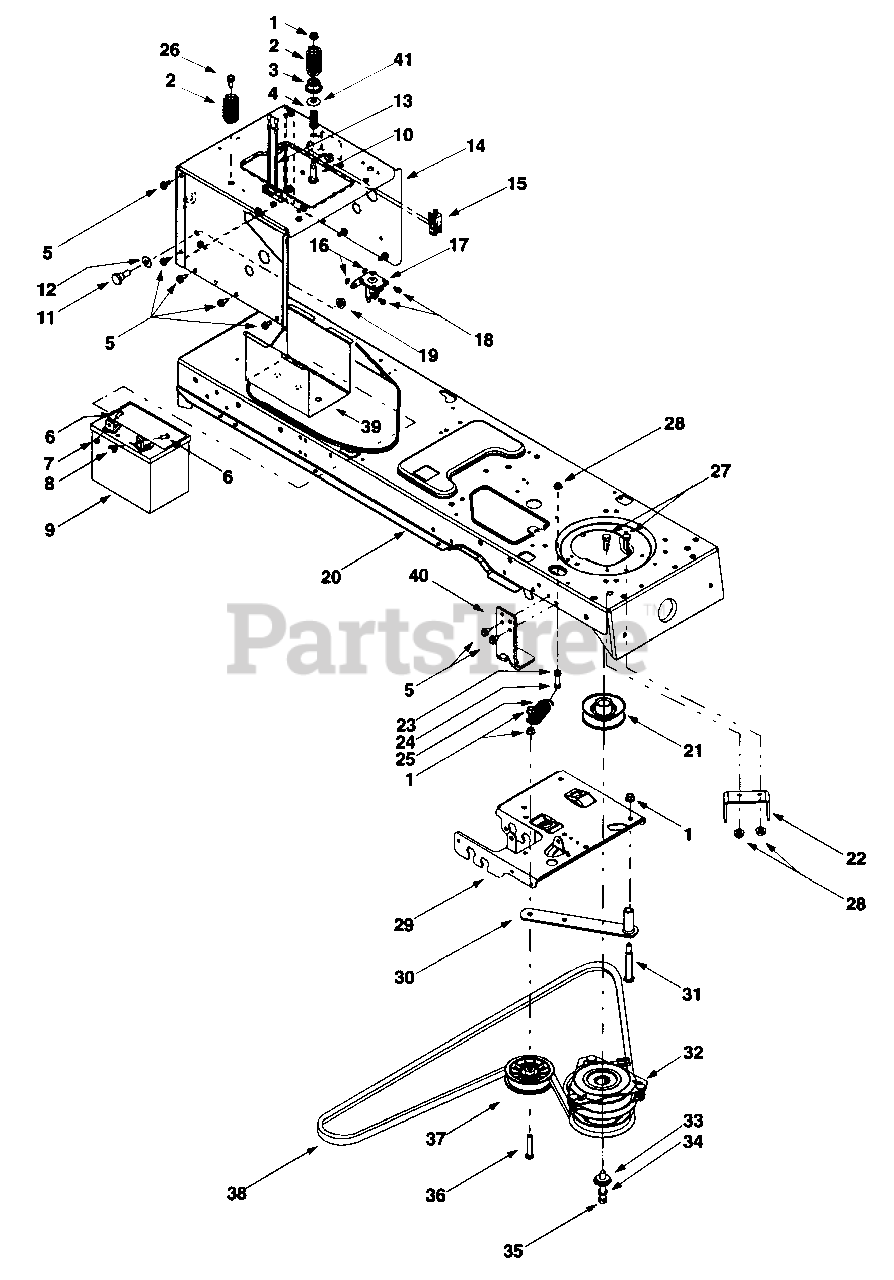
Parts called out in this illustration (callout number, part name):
1	Flange Lock Nut, 3/8-16
2	Compression Spring, 1.318 x 2.37
3	Spacer Cup, 1.5 OD
4	Compression Spring, .66 OD x 1.5
5	Self Tapping Screw, 5/16-18 x .625
6	Hex Cap Screw, 1/4-20 x .62
7	Hex Sems Nut, 1/4-20
8	Wing Nut, 1/4-20
9	12-volt Battery, 270 CCA
10	Shoulder Screw, .5 x 1.25, 3/8-16
11	Shoulder Screw, .625 x .5, 7/16-20
12	Bell Washer, .45 x 1.0 x .062
13	Battery Strap
16	Lock Washer, 1/4
17	Solenoid, 12-Volt, 100 Amp
18	Self Tapping Screw, 1/4-20 x .5
19	Flange Lock Nut, 7/16-20
24	Hex Cap Screw, 5/16-18 x 1.75 (Grade 5)
25	Extension Spring, 1.2 OD x 3.638
26	Self-tapping Screw, 5/16-18 x .875
27	Hex Cap Screw, 5/16-18 x .625
28	Flange Lock Nut, 5/16-18
29	Steering Support Bracket
31	Shoulder Screw, 1/2 Diameter x 2.5
32	Electric PTO Clutch
33	Shoulder Spacer, 1.38 x .445 x .36
34	Lock Washer, 7/16
35	Hex Cap Screw, 7/16-20 x 3.25 (Grade 5)
36	Hex Cap Screw, 3/8-16 x 2.25 (Grade 5)
37	Flat Idler Pulley, 3.5 OD
38	PTO Belt
